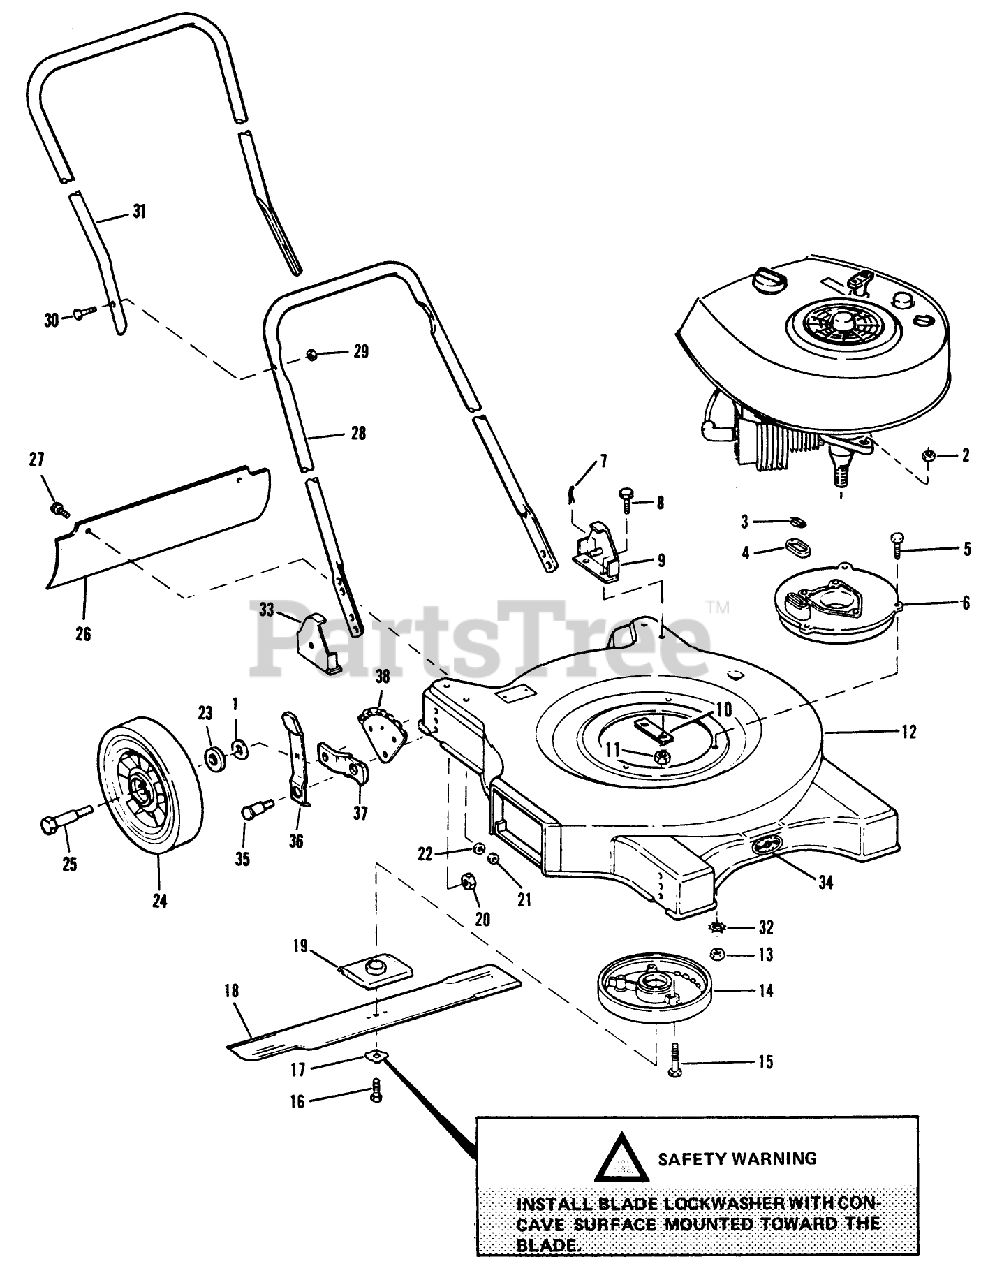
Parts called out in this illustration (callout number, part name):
1	WASHER WROUGHT
2	NUT-LOCK F
4	GASKET S
6	Muffler-Top Half
7	HAIR PIN
11	NUT-LOCK F
12	Housing
13	NUT-LOCK F
14	Muffler-Bottom Half
15	Bolt-Muffler
17	LOCKWASHER
20	LOCKNUT
21	LOCKNUT E
23	WASHER-PLAIN
24	WHEEL&TIRE ASSY
28	Cover Plate
29	LOCKNUT E
32	Lockwasher
35	Screw, Height Adjuster
37	Arm Height Adjuster
38	Back Plate
